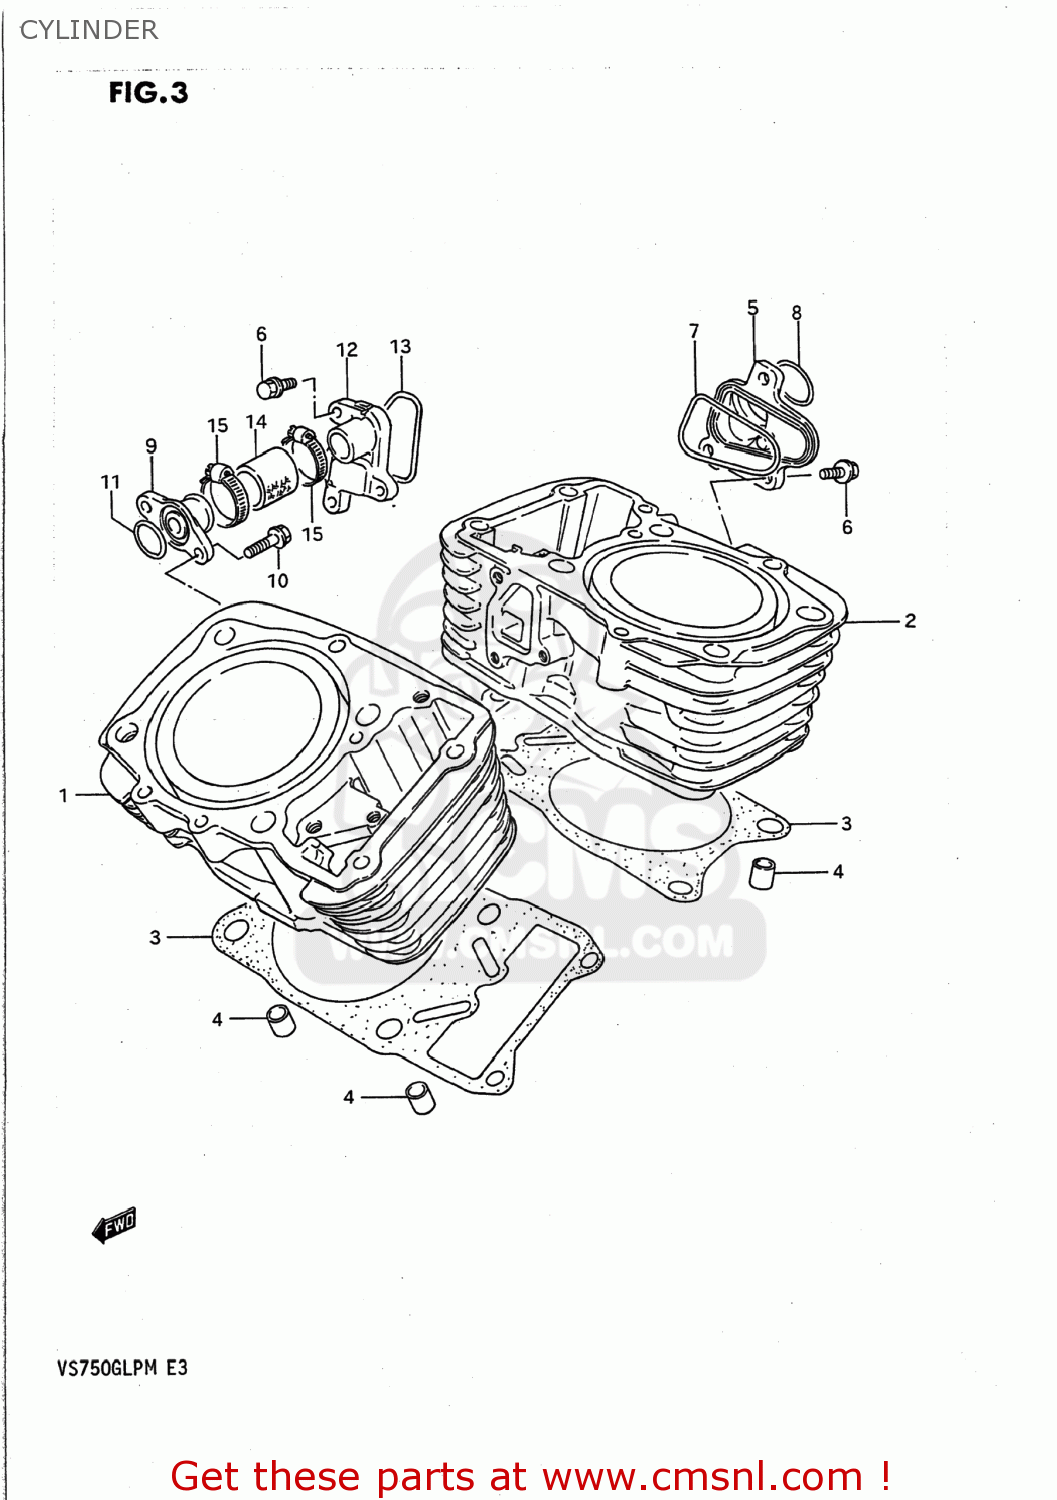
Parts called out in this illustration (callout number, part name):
1	CYLINDER,FR
2	CYLINDER,REAR
3	GASKET,CYLINDER (MCA)
4	PIN
5	CHAMBER,WATER,INLET
6	BOLT
7	O RING,INLET WATER CHAMBER
8	O RING(D:2.3,ID:24.4)
9	UNION,WATER INLET
10	BOLT
11	O RING(D:2.4,ID:15.8)
12	CHAMBER,WATER,OUTLET
13	O RING,OUTLET WATER CHAMBER
14	HOSE,RADIATOR
15	CLAMP
